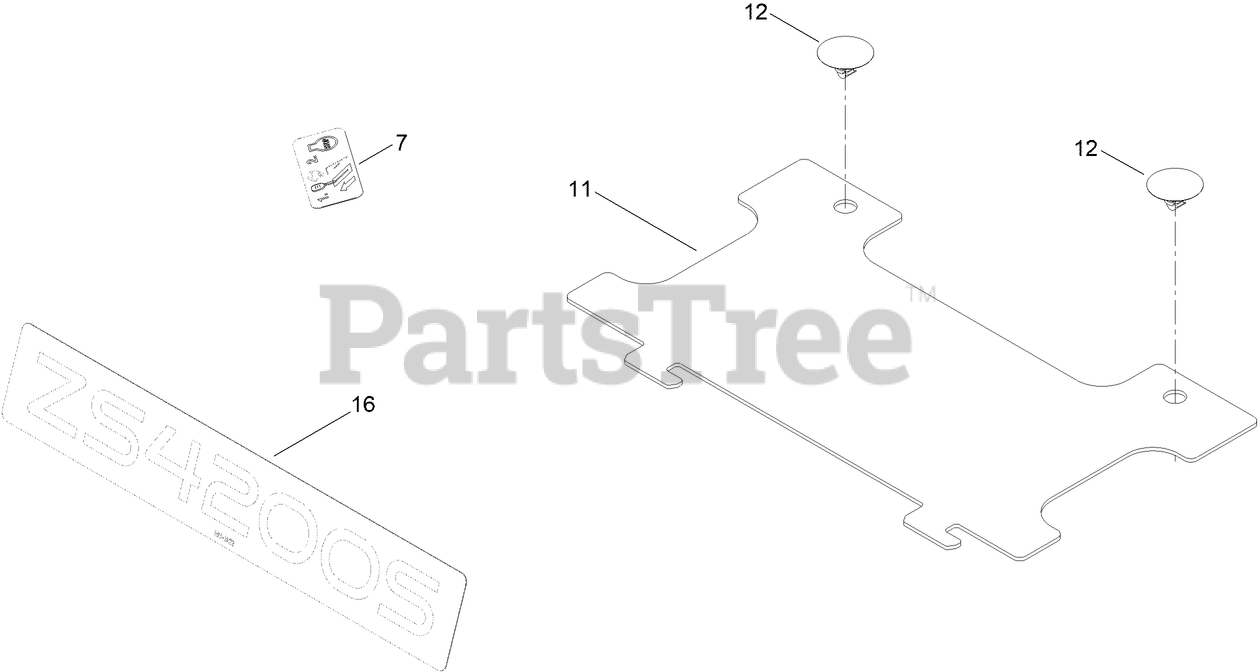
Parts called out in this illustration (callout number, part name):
7	DECAL-SHUTDOWN, CE
11	SHIELD
12	RIVET-PLASTIC
16	DECAL ZS4200S
